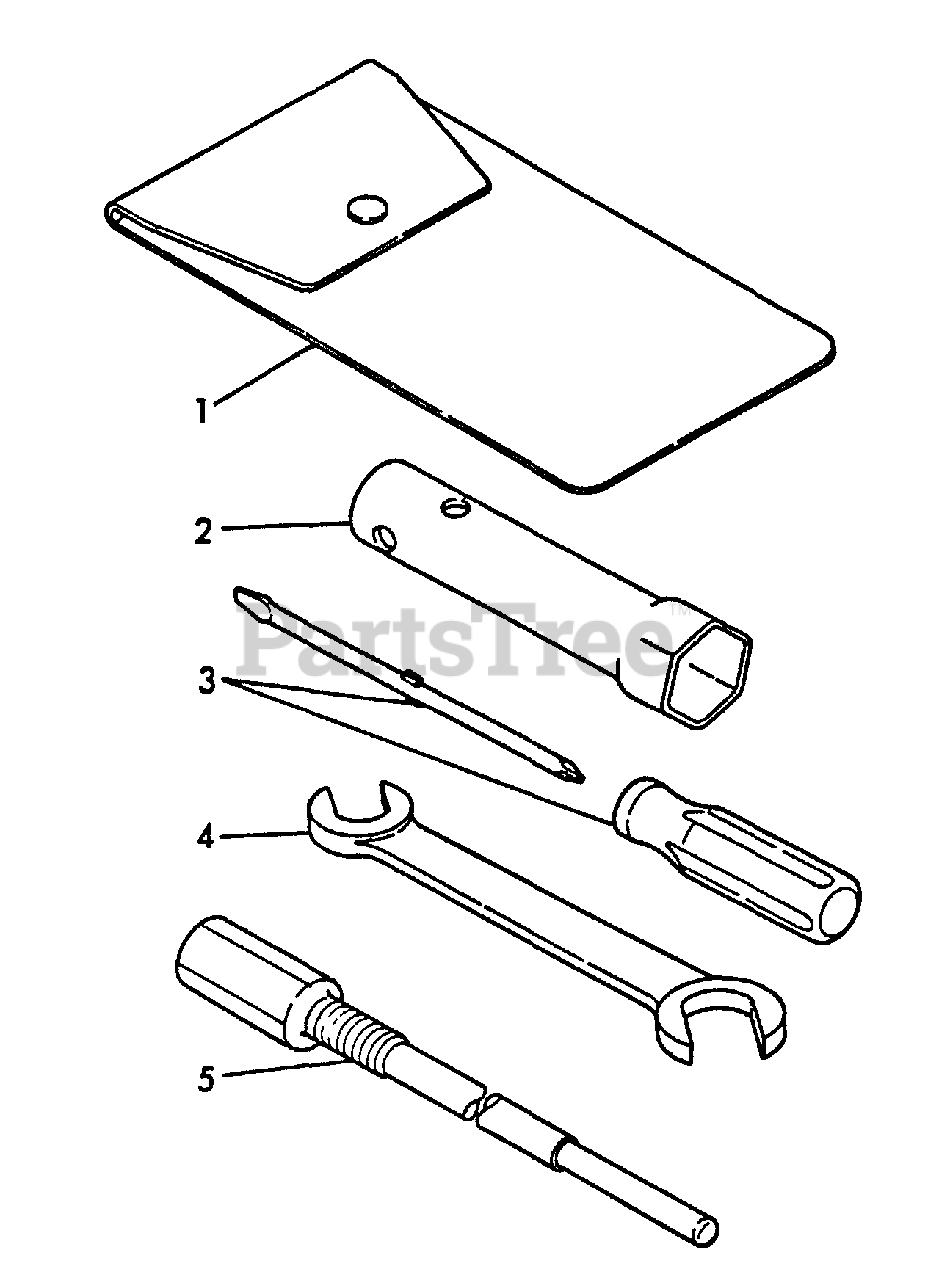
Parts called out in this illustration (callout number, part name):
1	BAG, TOOL
2	SOCKET WRENCH - 21mm
3	SCREWDRIVER
4	SPANNER - 10X12mm
5	TOOL, ROTOR REMOVAL
